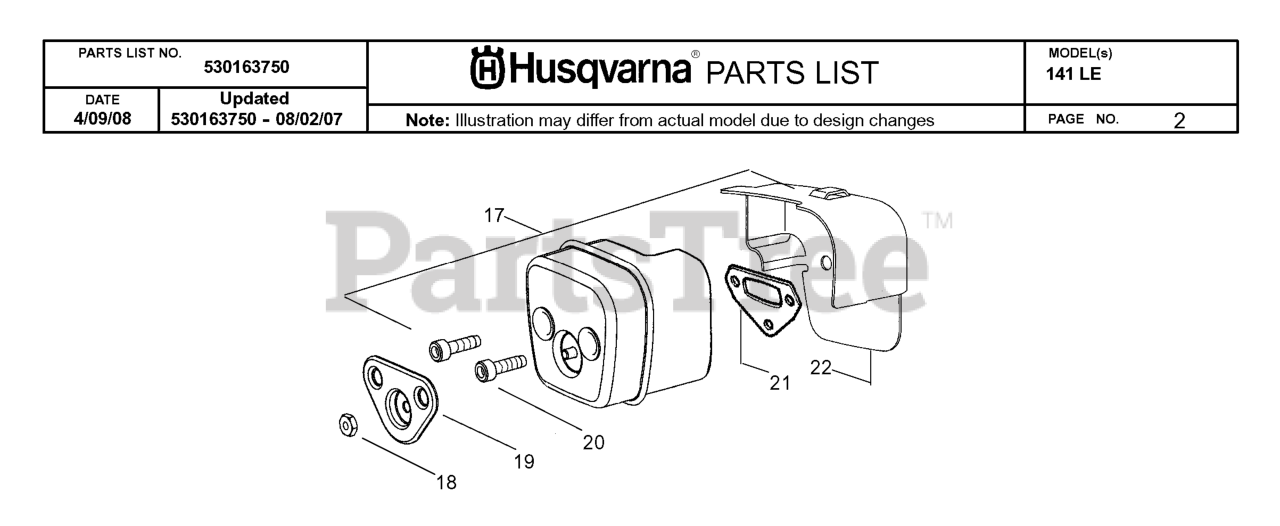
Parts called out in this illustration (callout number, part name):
17	MUFFLER KIT
18	NUT-BRASS
19	COVER BOLT
20	SCREW MUFFLER
21	GASKET-MUFFLER
22	BACKPLATE, MUFFLER
